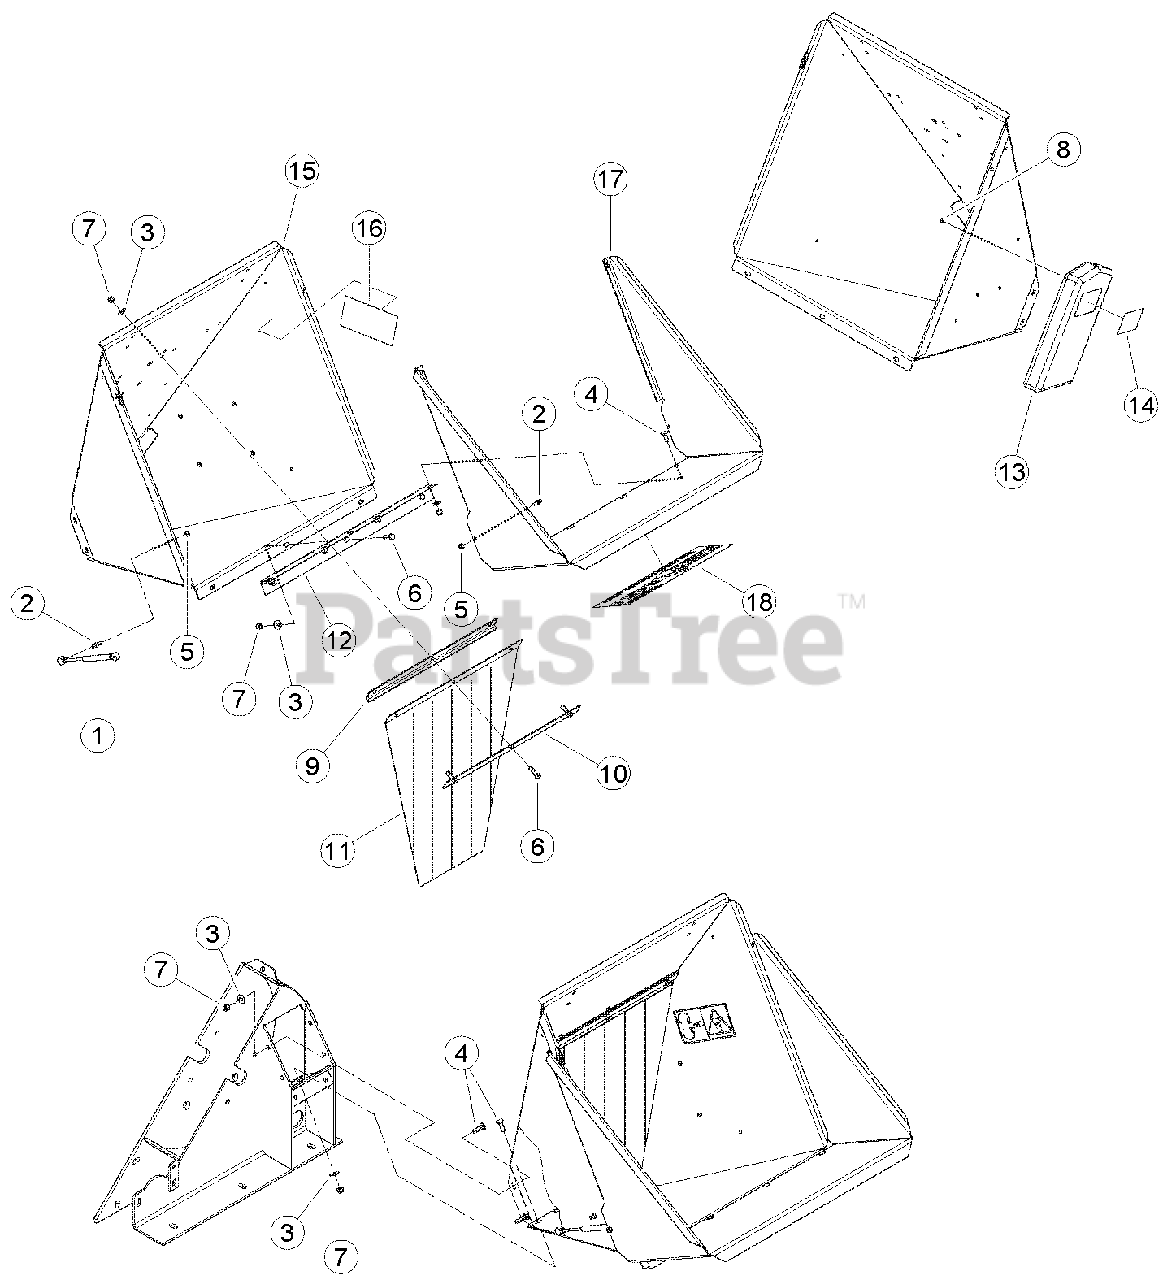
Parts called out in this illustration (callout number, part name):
1	SPRING, GAS 60 PSI
2	STUD, BALL .39
3	WASHER, 3/8 FLAT ZP
4	BOLT, 3/8 X 1 CRG GR5 NC ZP
5	NUT, 5/16 NE NYLOCK ZP
6	BOLT, 3/8 X 1-1/4 HEX HD GR5 ZP
7	NUT, 3/8 NE NYLOCK ZP
8	RIVET, 1/4 X 1/2 DOME HD BLIND SS
9	ANGLE, FLAP ANCHOR
10	STRIP, FLAP RETAINER
11	FLAP, CHIPPER CHUTE
12	HINGE, EXTENSION TRAY
13	ASSEMBLY, MANUAL CONTAINER SERVICE PART
14	DECAL, MULTILINGUAL MANUAL
15	ASSEMBLY, 5 INCH CHIPPER CHUTE SERVICE PART
16	DECAL, BLADE DANGER ISO
18	DECAL, BEARCAT WEB
